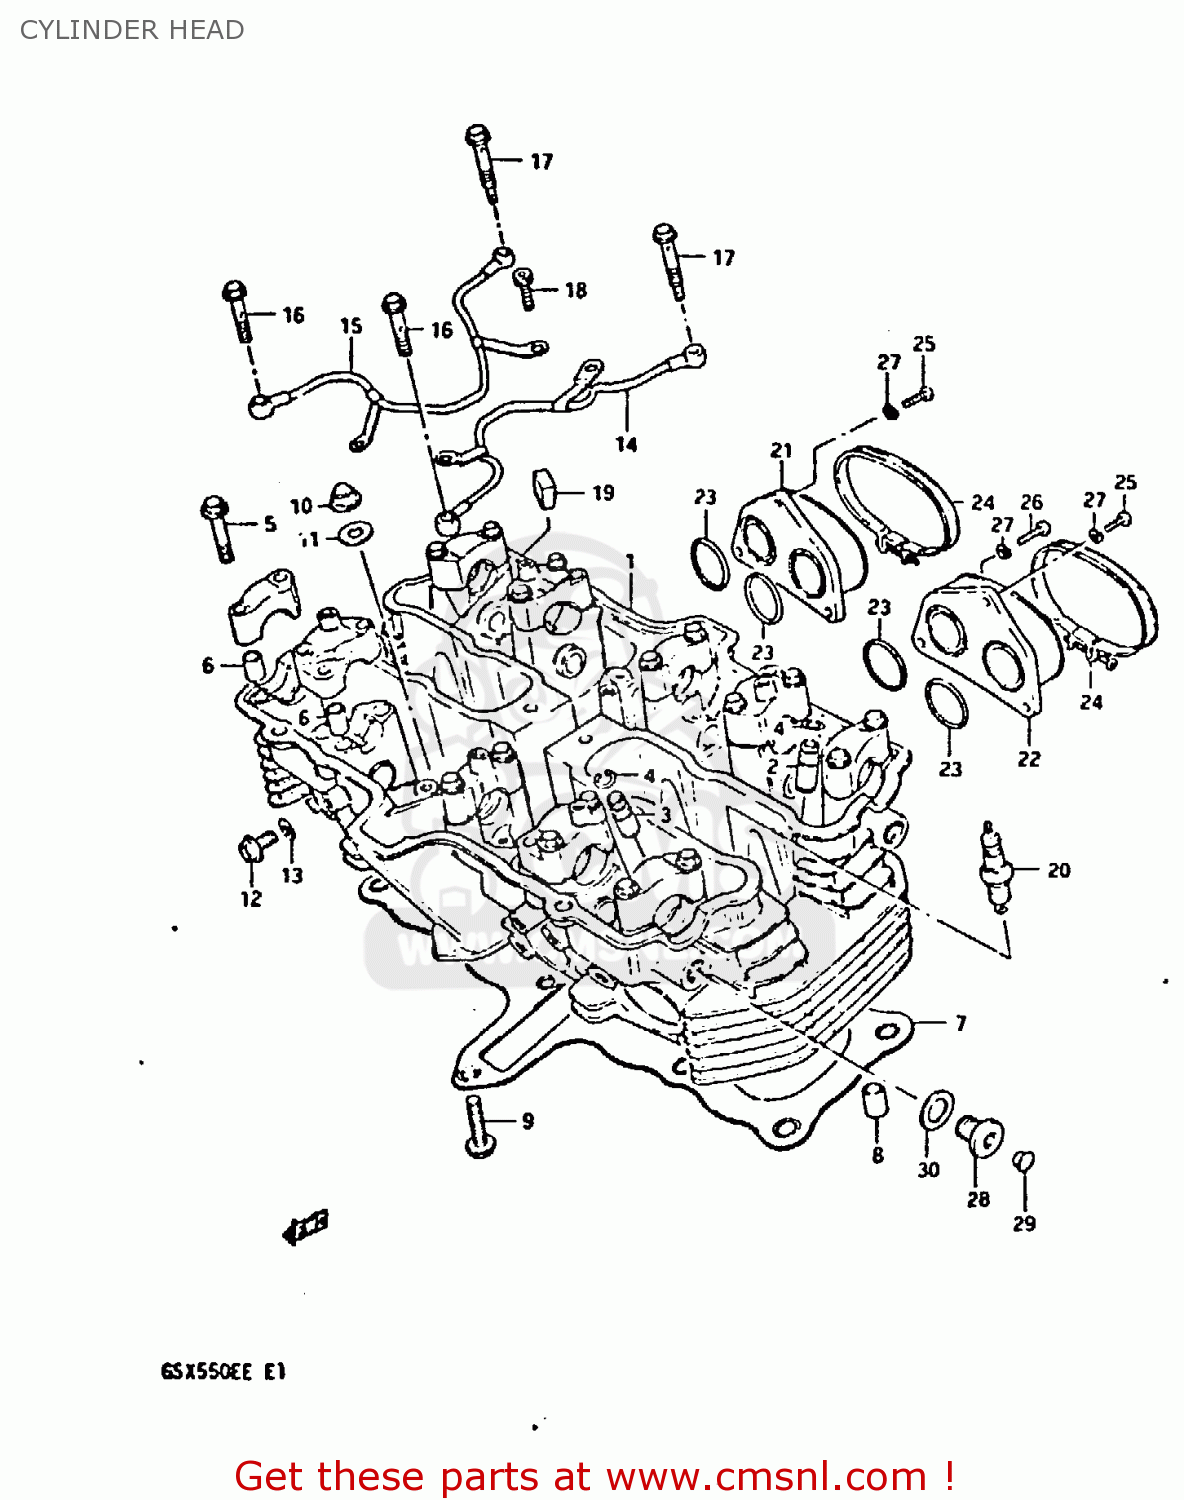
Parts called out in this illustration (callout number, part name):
1	HEAD ASSEMBLY,CYLINDER
2	GUIDE,VALVE
3	GUIDE,VALVE
4	RING,SNAP
5	BOLT(6X39)
6	PIN(6.2X8X11)
7	GASKET,CYLINDER HEAD (NAS)
8	PIN
9	BOLT
10	NUT
11	GASKET(8.5X20X2.3) (NAS)
12	BOLT 6X12
13	GASKET(6.2X13X1.2) (NAS)
14	PIPE,OIL CYLINDER HEAD
15	PIPE,OIL CYLINDER HEAD
16	UNION
17	BOLT,UNION
18	BOLT
19	PAD,CYLINDER
20	PLUG,SPARK(DR8ES)
21	PIPE,INTAKE,R
22	PIPE,INTAKE,L
23	O-RING (D:2.4 ID:29.7)
24	CLAMP
25	SCREW
26	SCREW
27	LOCK WASHER
28	PLUG
29	CAP(OD:12)
30	GASKET(14X19.2X2) (NAS)
